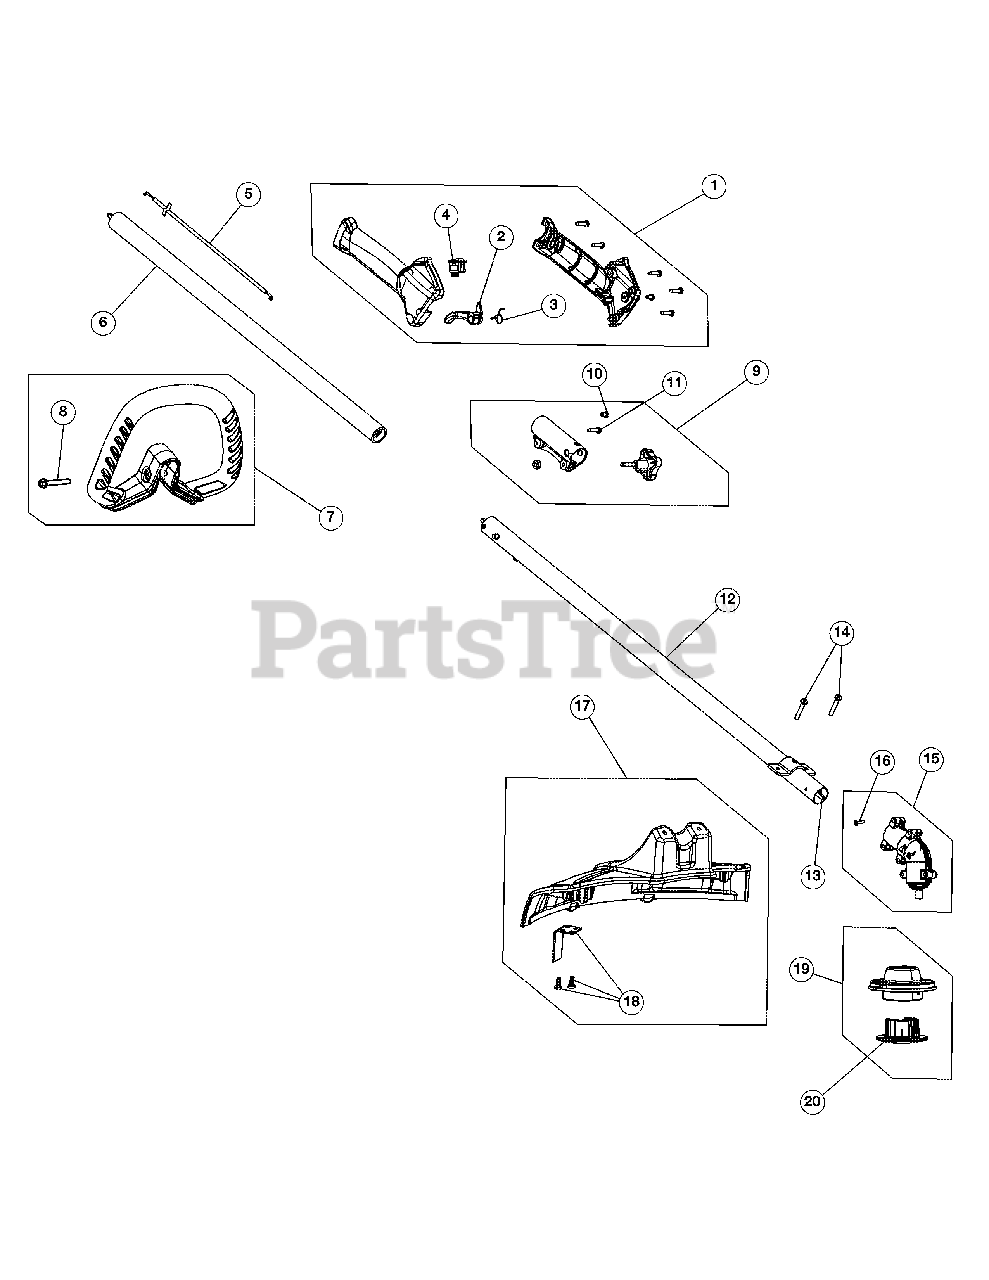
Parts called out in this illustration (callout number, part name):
1	Throttle Housing Assembly (Incl. 2-4)
2	Throttle Trigger
3	Throttle Trigger Spring
4	Switch Assembly
5	Throttle Cable Assembly
6	Upper Drive Shaft Assembly
7	D-Handle Assembly (Incl. 8)
9	Split Boom Coupler (Incl. 10-11)
10	Coupler Anti-Rotation Screw
11	Coupler Bolt
12	Lower Drive Shaft Housing
13	Lower Flexible Drive Shaft
14	Shield Mount Screw Assembly
15	Gearbox Assembly (Incl. 16)
16	Screw
17	Shield Assembly (Incl. 18)
18	Blade Assembly
19	Cutting Head Assembly (Incl. 20)
20	Cutting Head Cap
